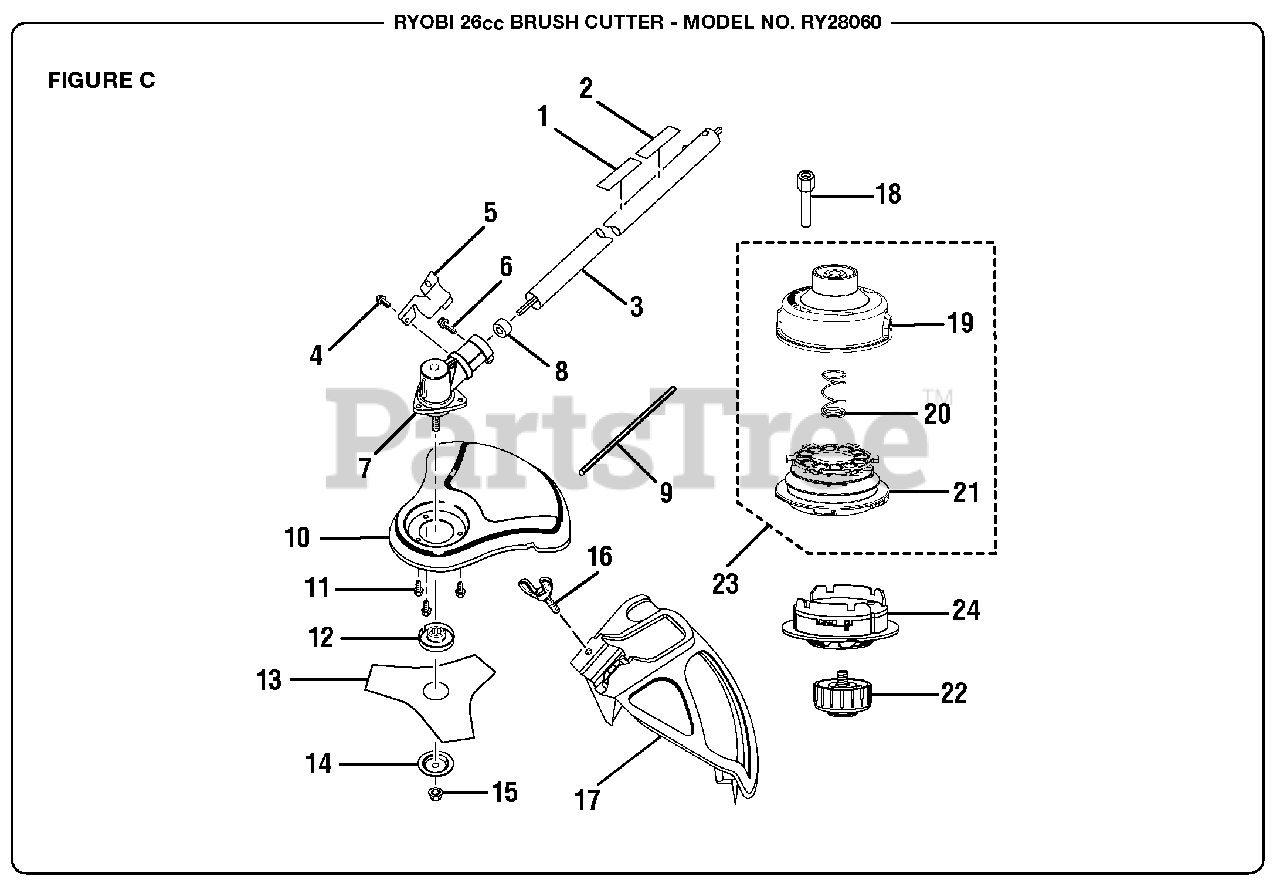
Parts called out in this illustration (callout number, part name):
1	Expand-it Label
2	Brushcutter Safety Label
3	Straight Shaft Assy
4	Screw (10-24 x 5/8 in.)
5	Clamp
6	Screw (1/4-20 x 1-1/4 in.)
7	Gear Head
9	Gear Head Locking Tool
10	Brushcutter Guard
11	Screw (10-24 x 1/2 in.)
12	Flanged Washer
14	Cupped Washer
15	Blade Nut
16	Screw (1/4-20 x 1-1/4 in.)
17	Grass Deflector Assy (Incl. Key No. 16)
19	String Head Housing
20	Spring
21	Spool
22	Spool Retainer
23	String Head Assembly (Incl. Key Nos. 19-21)
24	Dual Spool TM Fixed Line String Head Insert
